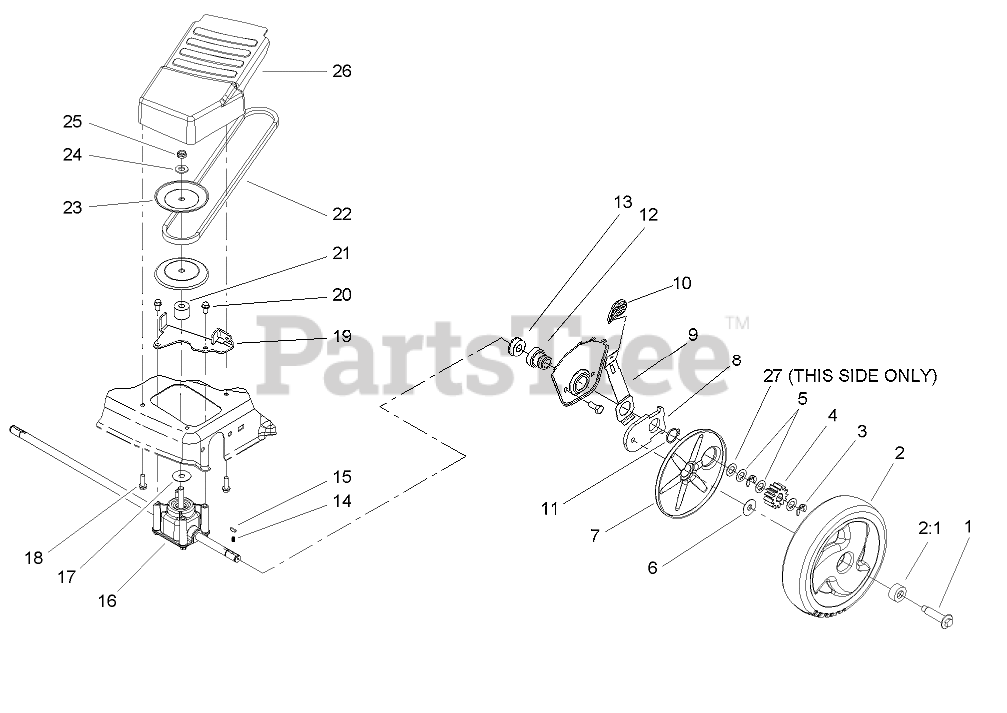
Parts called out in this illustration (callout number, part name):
1	BOLT-SHOULDER
2	Wheel Gear ASM
2:1	BUSHING
3	RING-CLIP, LOCKING
4	Gear-Pinion, 13t
5	Washer-Thrust
6	WASHER-STEPPED
7	COVER
8	ARM-PIVOT, FRONT
9	Arm-Spring
10	Knob-Lever, HOC
11	RING-RETAINING
12	RETAINER-BEARING, HOC
13	BEARING-BALL
14	SPRING-COMPRESSION
16	TRANSMISSION ASM
17	WASHER-PLAIN
18	SCREW-HWH
19	BRACKET-PIVOT, FWD
20	SCREW-HWH
21	SPACER
22	BELT-V
23	Pulley-Half, Front
24	WASHER-FLAT
25	NUT-HEX
26	Cover-Belt, Front
27	WASHER-PLAIN
